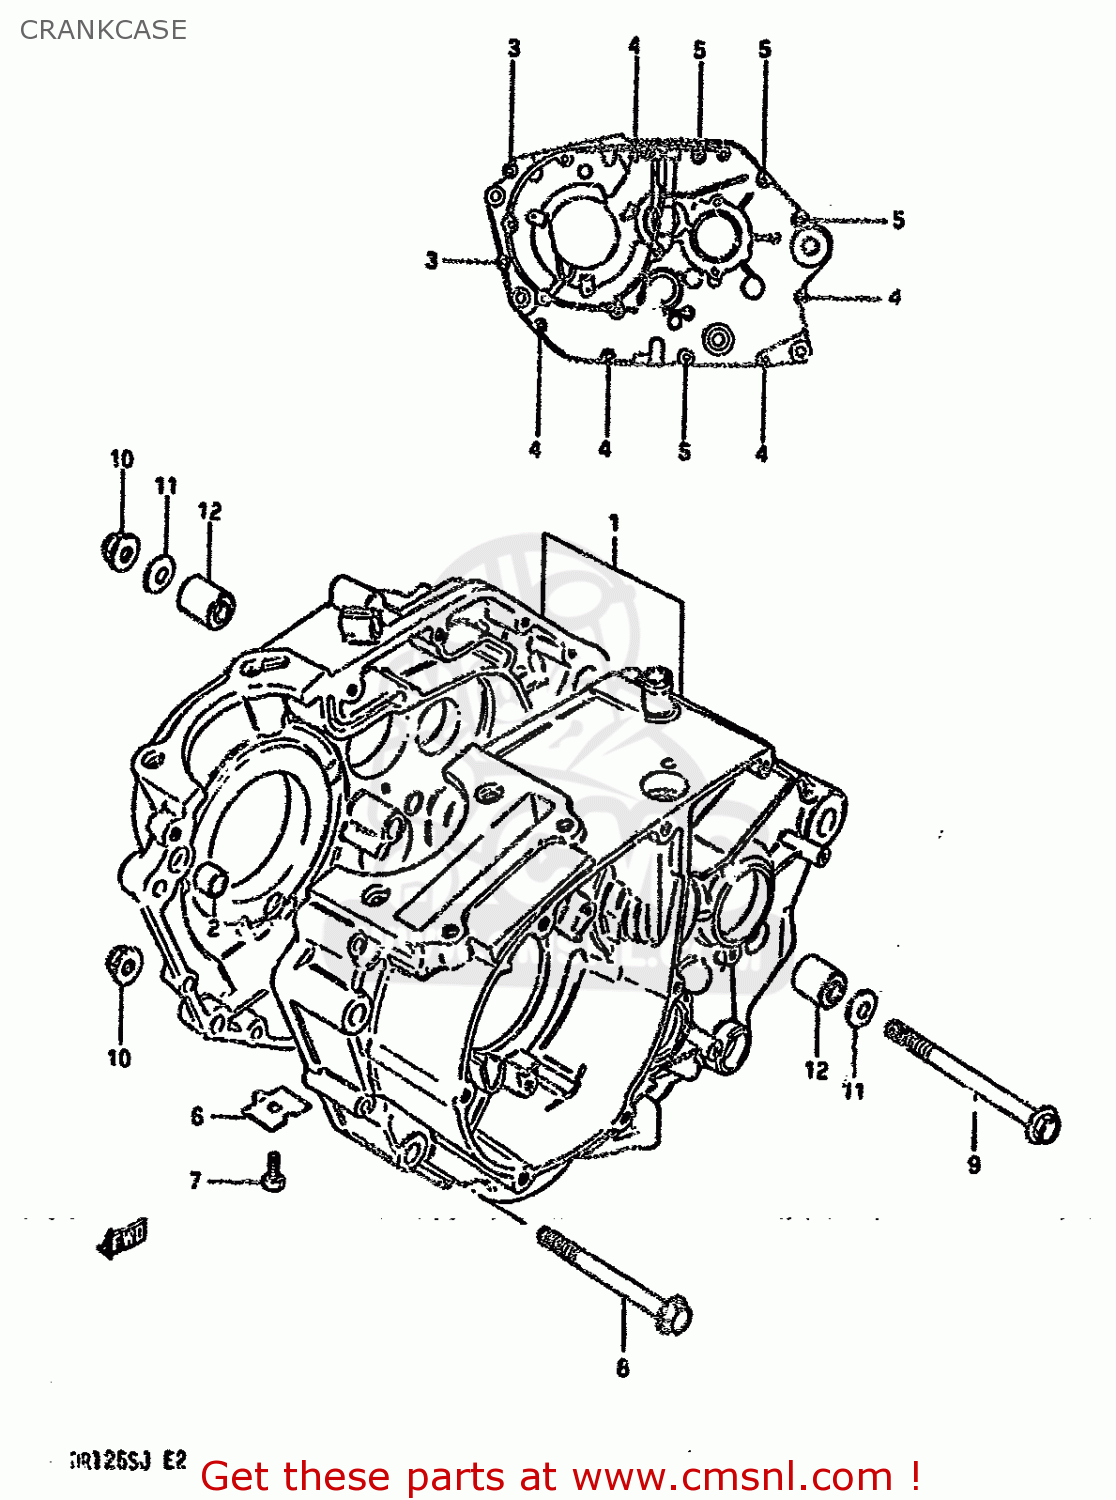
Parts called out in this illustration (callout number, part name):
1	CRANKCASE SET
2	PIN
3	BOLT
4	BOLT (6X60)
5	BOLT (6X75)
6	PLATE,OIL GALLERY PLUG
7	BOLT
8	BOLT(8X80)
9	BOLT L:115
10	NUT
11	WASHER
12	BUSH(8.4X18X16)
